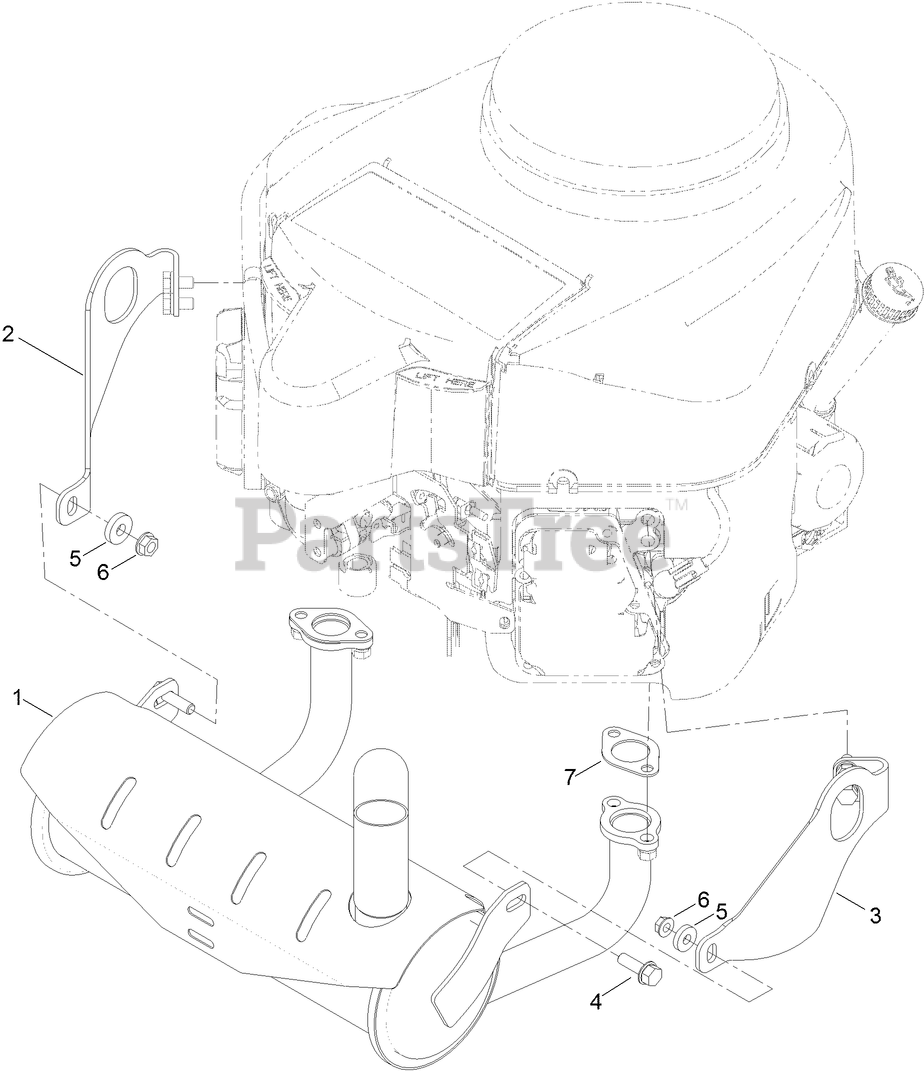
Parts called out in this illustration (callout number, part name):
1	MUFFLER
2	BRACKET-MUFFLER, RH
3	BRACKET-MUFFLER, LH
4	SCREW-HHF
5	SPACER
6	NUT-HF
7	GASKET-EXHAUST
